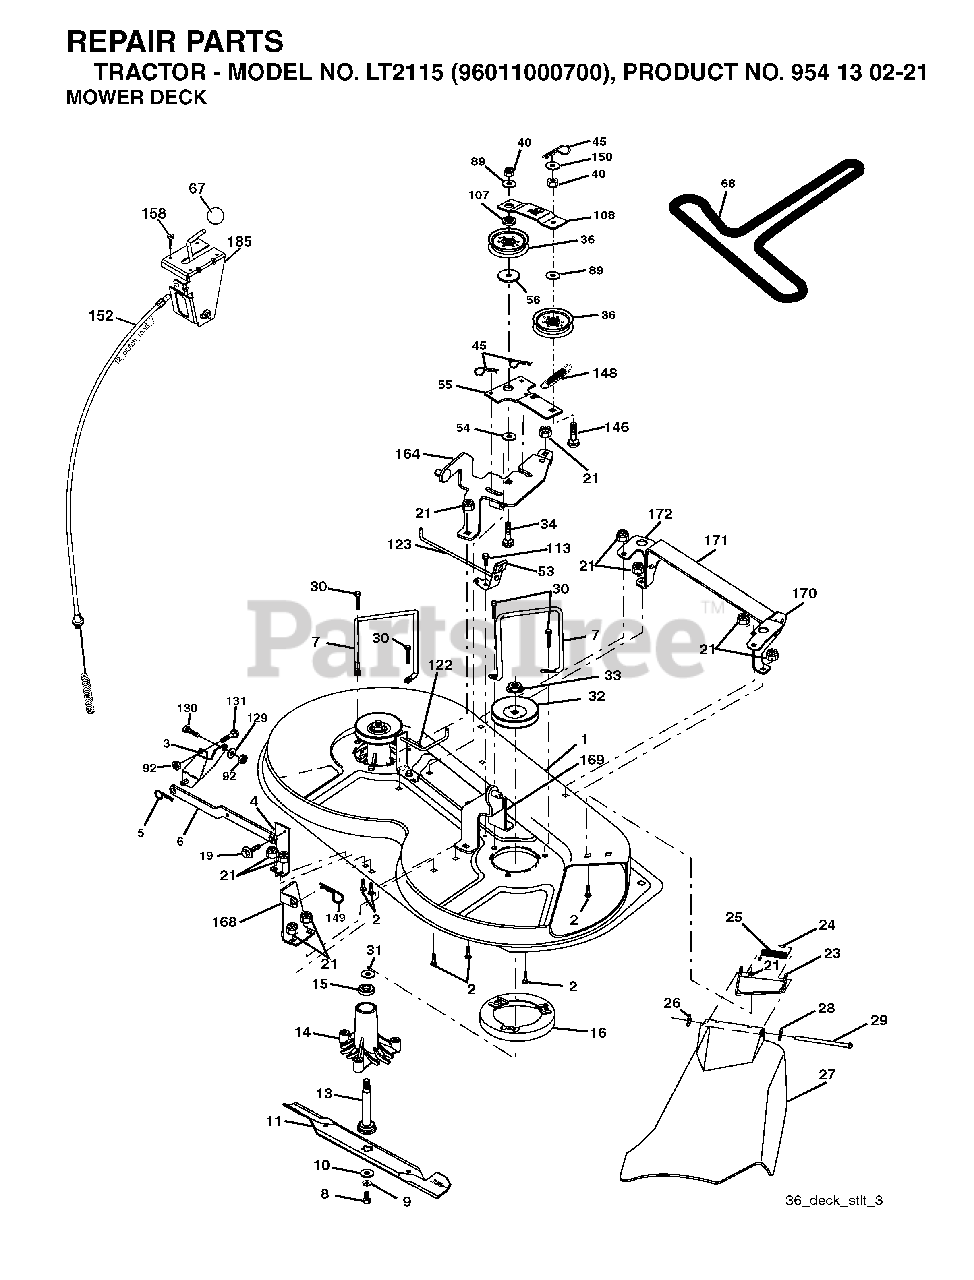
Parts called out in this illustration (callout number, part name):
2	BOLT
3	BRKT ASM SWAY BAR
5	RETAINER-SPRNG RB
6	BAR SWAY DECK
7	KEEPER LH
8	BLADE BOLT
9	LOCKWASHER
10	WASHER.BLADE
11	BLADE, HI-LIFT 36" PREMIUM
13	SHAFT ASM VENT
14	HSG MANDREL
16	STRIPPER, MWR ROUND
19	BOLT SHD 5/16-18
21	LOCKNUT
23	BRACKET ASM DEFLECTOR
24	CAP-SLEEVE LT
25	SPRING TORSION
26	NUT PUSH M
28	WASHER
29	HINGE ROD
30	SCREW, WASHER HEAD
31	WASHER.SPACER.MANDREL
32	PULLEY, MANDREL
33	NUT, FLG TOPLOCK 9/16"
34	BOLT
36	FLAT IDLER PULLEY
40	LOCKNUT
45	RETAINER M
53	BRAKE ASSEMBLY
55	IDLER ARM
56	SPACER.RETAINER.MOWER
67	KNOB T (3/8 HOLE)
68	V-BELT.MOWER.
89	WASHER
92	NUT
107	SPACER.IDLER.ARM
108	STIFFENER.IDLER.ARM
129	WASHER
131	BOLT D
146	BOLT, CARRIAGE IDLER
148	IDLER RETURN SPRING
149	SPRING.RETAINER.YELLOW.ZINC
150	WASHER LT
158	SCREW
171	BRACE
185	HEAD ASM. CABLE CLUTCH
